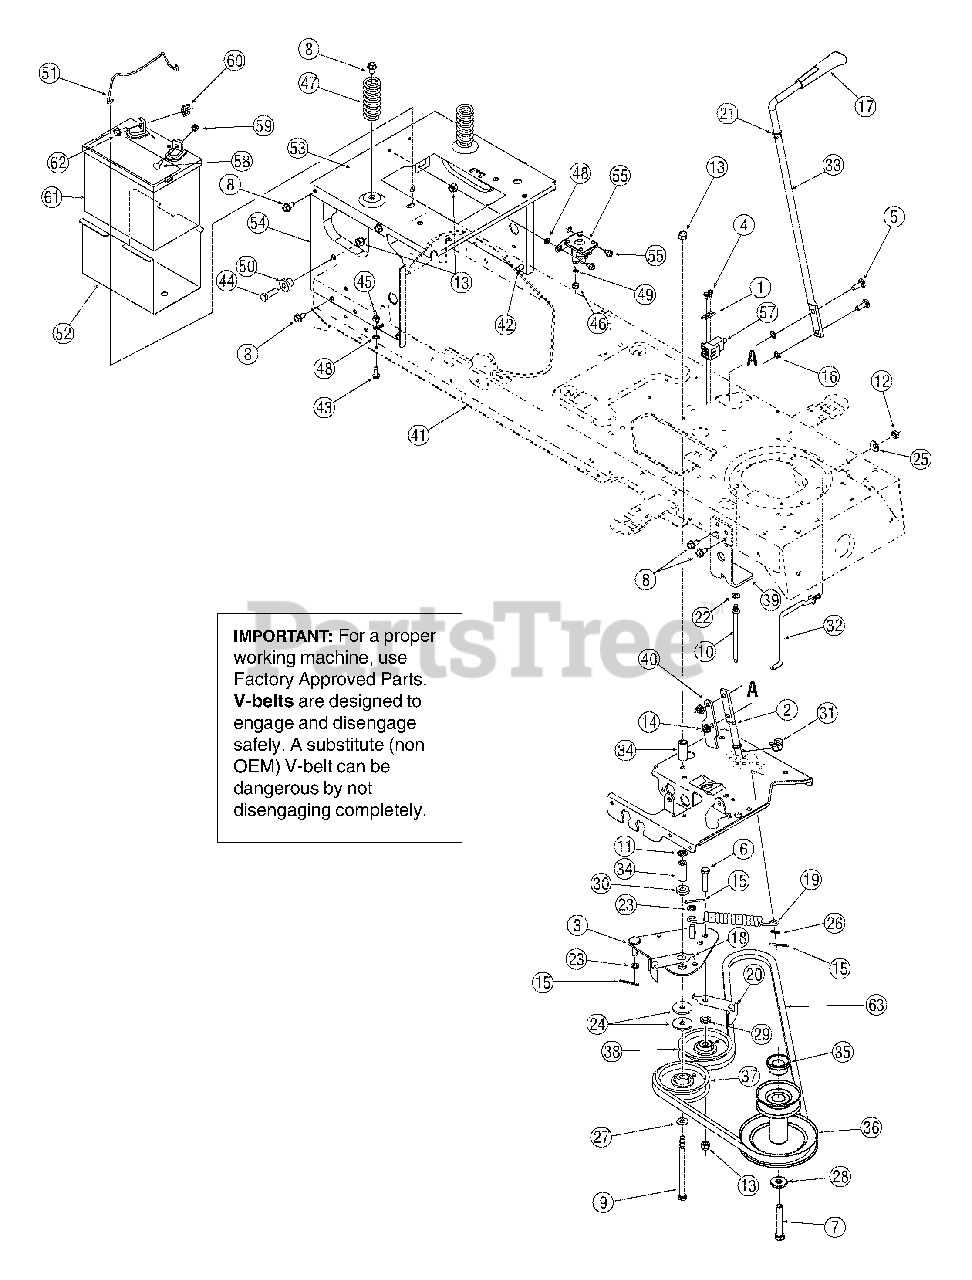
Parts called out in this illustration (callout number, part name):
1	Plate, Switch
2	Lever Assembly, Engagement
4	Screw, #10-16, 0.500
5	Screw, Carriage, 5/16-18, 1.00
6	Screw, 3/8-16, 1.75, Gr5
7	Screw, 7/16-20, 2.75, Gr5
8	Screw, 5/16-12, 0.750
9	Screw, 3/8-16, 5.50, Gr5
10	Pin, Belt Guard, 5/16 x 4.75
11	Nut, Push, 3/8
12	Nut, Flange Lock, 5/16-18, Gr F, Nylon
13	Nut, Flange Lock, 3/8-16, Gr F, Nylon
14	Nut, Flange Lock, 5/16-18, Gr5
15	Pin, Cotter, 1/8 x 1.25
16	Nut, Speed,.3125 ID
17	Knob, PTO
18	Belt Guard
19	Spring, Extension,.75 OD x 6.75
20	Belt Guard
21	Washer, Flat,.510 x.750 x.033
22	Washer, Lock, 5/16
23	Washer, Flat,.385 x.62 x.063
24	Washer, Flat,.390 x 1.500 x.134
25	Washer, Bell,.340 x.872 x.060
26	Washer, Flat,.344 x.688 x.065
27	Washer, Flat,.406 x.875 x.059
28	Washer, Flat,.450 x1.250 x.164
29	Washer, Flat,.407 x.812 x.135
30	Spacer, Shldr, 1.00 x.38 x.38
31	Bearing, Flange, Hex Split.500 ID
32	Keeper Rod, Belt
34	Spacer,.385 ID x.635 OD x 1.54
35	Spacer, 1.010 x 1.400 x.825
36	Pulley, Engine, 3.39 x 6.12 Diameter
37	Pulley, Idler, V-type 5/8 x 4.0 Diameter
38	Pulley, Idler, 3.50 Diameter
43	Screw, 1/4-20, 0.750
44	Screw, 3/8-16, 1.25, Gr5
45	Nut, Flange Lock, 1/4-20, Gr F, Nylon
46	Nut, Hex, 1/4-20, Gr5
47	Spring, Compression, 1.28 OD x 3.125
48	Washer, Lock, 1/4, External
49	Washer, Lock, 1/4
50	Spacer, Shoulder,.38 x 1.0 x.70
51	Hold Rod, Battery
55	Screw, 1/4-20, 0.50
56	Solenoid, 12V, 100 Amp
57	Switch, Interlock
58	Screw, Carriage, 1/4-20,.75, Gr5
59	Nut, Sems, 1/4-20
60	Nut, Wing, 1/4-20
61	Battery, 235 CCA
62	Screw, Shoulder,.250 x.150, 1/4-20
63	V-Belt, PTO
